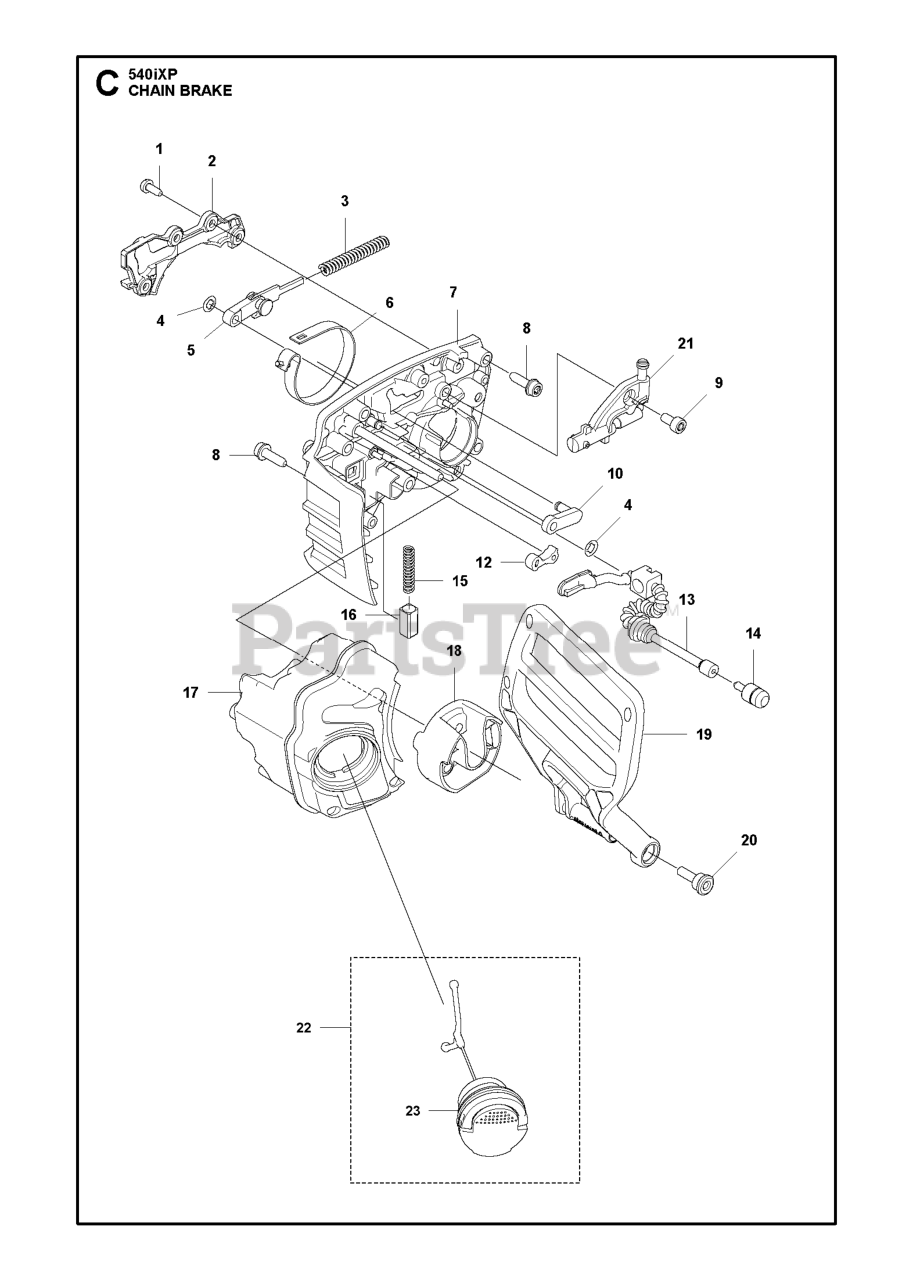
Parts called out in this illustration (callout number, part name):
2	Covers
4	Washers
6	BRAKE BAND
7	CHASSIS
10	Drive Links
14	OIL PLUMMET
15	LOCK SPRING
17	Tanks
18	Hand Guard
21	OIL PUMP ASSY
22	TANK CAP ASSY
